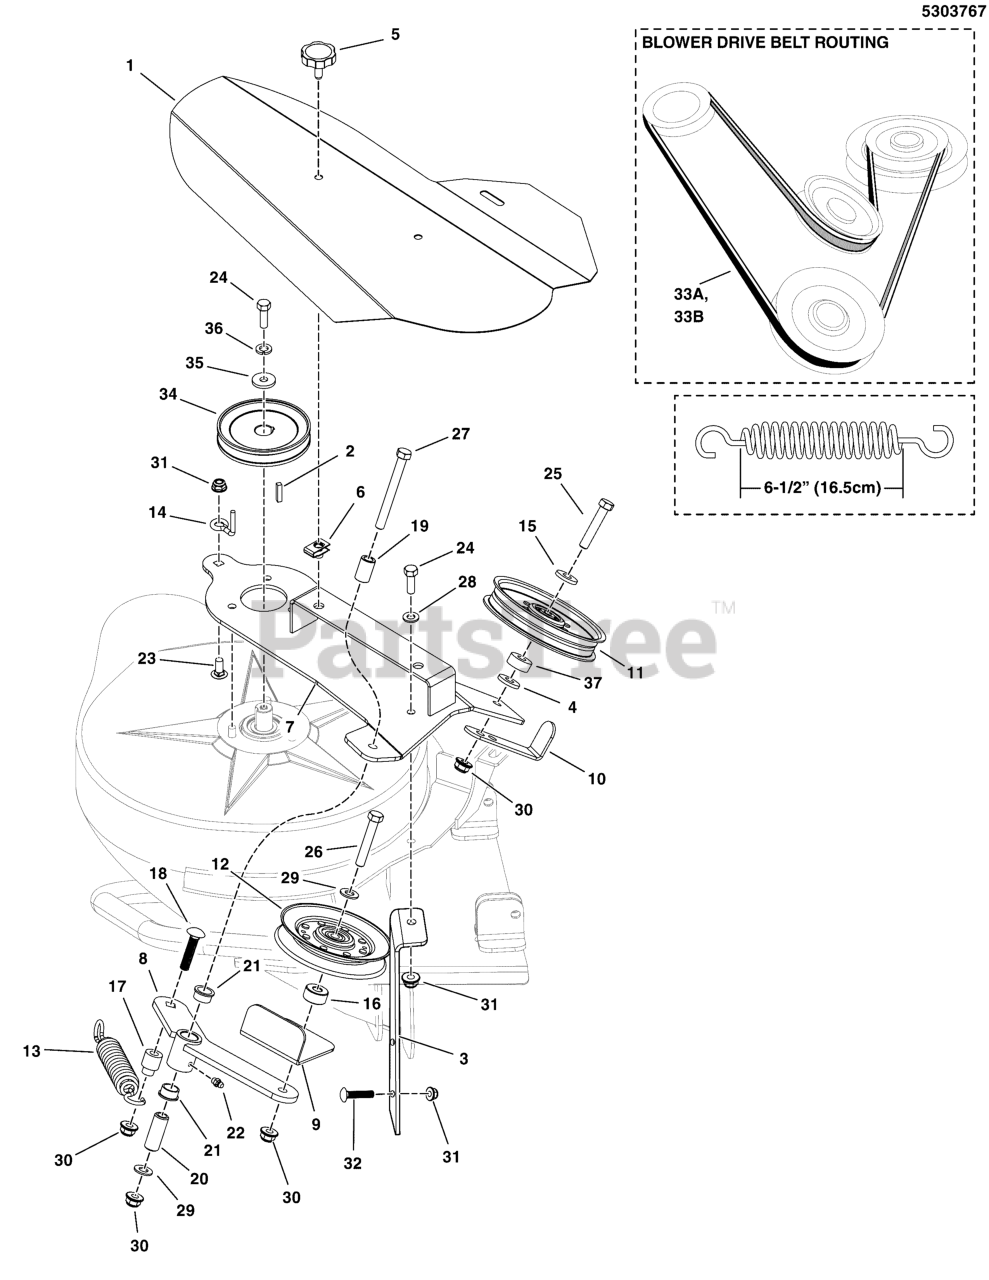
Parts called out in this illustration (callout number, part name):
1	HOOD W/ DECALS - TURBO PRO-MAX
2	KEY, 3/16" SQ. X 3/4
3	BRACKET, FRONT SUPPORT, 61" COM - BLK
4	WASHER, 3/8" Fender
5	KNOB, 5/16-18 X 1.00, ROSETTE BLACK
6	BODY CLIP, 5/16-18 7GA. MATERIAL
7	ASSEMBLY, PULLEY PLATE, T-MAX (52,61)
8	ASSEMBLY, IDLER ARM - TURBO-VAC
9	RETAINER, BELT, WIDE - BLK
10	RETAINER, BELT
11	PULLEY-IDLER 04.00 OD 0.378ID 1.06 W BRG
12	PULLEY-IDLER-V, 4.85OB, .38ID
13	SPRING-EXT, 1.04 ODX6.935LGX.148WR, BLK
14	BELT KEEP, .19 X 1.25 - BK
15	WASHER, .406X1.0X.134,FLT,TYPE A, ZINC/CLEAR
16	SPACER, .39 X 1.00 X .50, PM, CZ
17	SPACER,3/8X3/4X15/16
18	BOLT,3/8-16X1.750,SHORT NECK CRRG,ZC/CL
19	SPACER, .39 X .63 X 1.00, YZ
20	SPACER, .38 X .625 X 1.62, YZ
21	BUSHING-0.628IDX0.751ODX0.400LG PWDR MTL
22	GREASE FITTING, 1/4-28 Straight
23	BOLT, 5/16-18 X 3/4, CARRIAGE, GD5, CZ
24	BOLT, 5/16-18 X 1" GRD5 YZ
25	BOLT, 3/8-16 X 1-3/4" GD5 CZ
26	BOLT, 3/8-16 X 2-1/4" GD5 CZ
27	BOLT, 3/8-16 X 3-1/2" GD5 CZ
28	WASHER, 5/16" SAE
29	WASHER, 3/8 SAE
30	NUT, 3/8 - 16 HEX NYLOCK FLANGE
31	NUT, 5/16-18 HEX NYLOCK FLANGE NUT
32	BOLT, 5/16-18 X 1, CARRIAGE, GD5, CZ
33A	BELT, A SEC, 81.1"EL, ARAMID, WRPD
33B	V-BELT HA 83.10
34	PULLEY, COMMERCIAL PRO
35	WASHER-0.312(0.34IDX1.00ODX.13THK)BLK
36	WASHER, 5/16 LOCK YZ
37	SPACER-0.390ID 0.90 OD 0.34 LG P'MTL YEL
